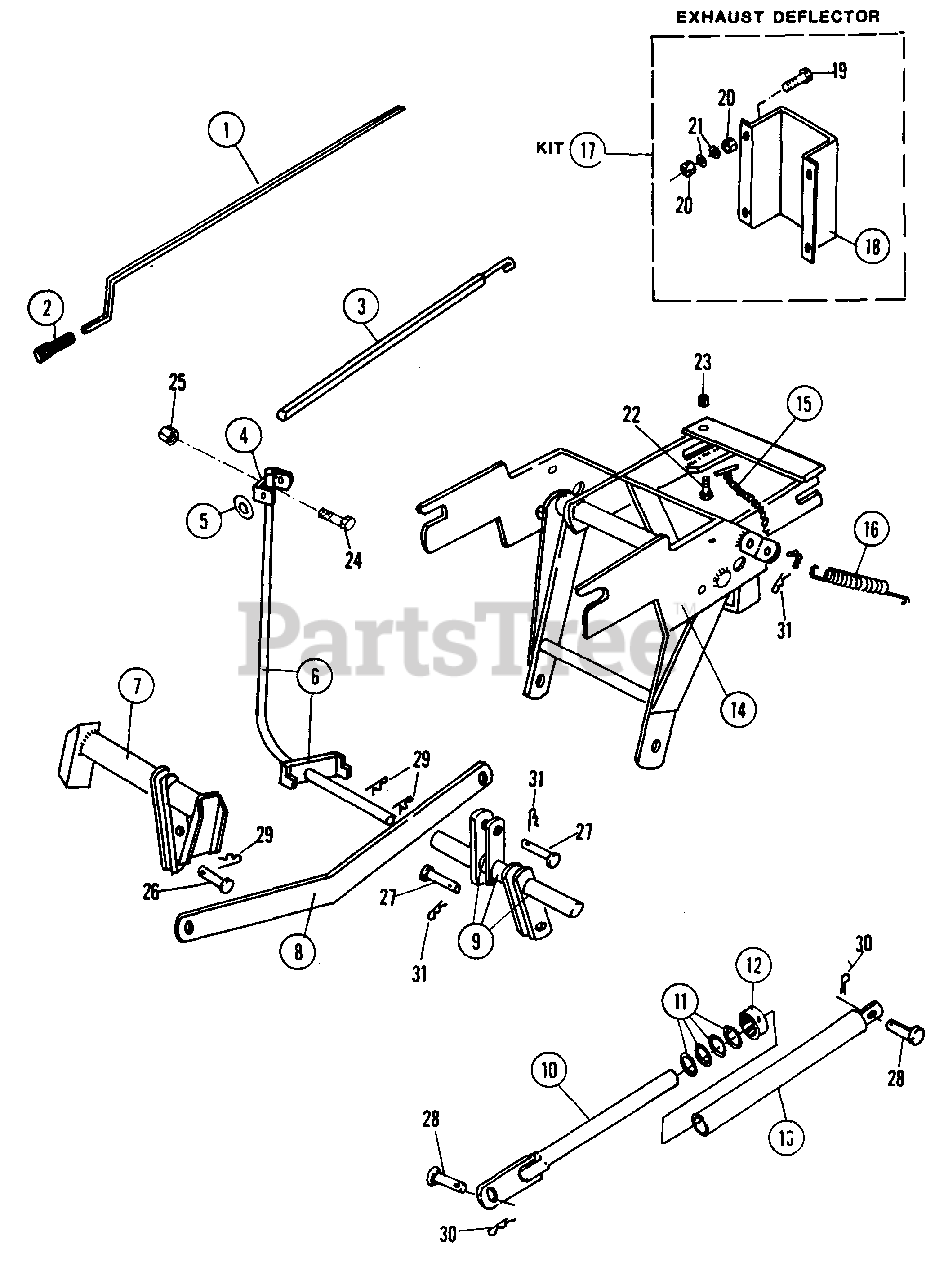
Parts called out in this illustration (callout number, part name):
1	ROD, CHUTE CRANK CONTROL
2	GRIP, HANDLE
3	EXTENSION, CRANK ROD
4	GUIDE, CRANK CONTROL
5	DECAL, CHUTE CONTROL
6	ROD, CRANK SUPPORT
7	LINKAGE, BELLCRANK
8	STRAP, LINK
9	LINKAGE, LIFT
10	ROD, LIFT
11	WASHER, LIFT STOP ADJUSTING
12	COLLAR, LIFT TUBE
13	TUBE, LIFT
14	BRACKET, SNOW THROWER MOUNTING
15	CHAIN, TOGGLE
16	SPRING, LIFT ASSIST.
17	KIT, EXHAUST DEFLECTOR
18	PLATE, EXHAUST DEFLECTOR
19	BOLT, 1/4-20x1" HEX HEAD
20	NUT, 1/4-20 HEX
21	WASHER, 17/16x5/8x.049 FLAT
22	BOLT, 3/8cx1" HEX HEAD
23	LOCKNUT, 3/8c HEX
24	BOLT, 3/8-16x1-1/2 HEX HEAD
25	LOCKNUT, 3/8-16 HEX
26	PIN, LIFT RETAINING CLEVIS
27	PIN, LIFT LINK CLEVIS
28	PIN, LIFT TUBE CLEVIS
29	PIN, HAIR COTTER
30	PIN, COTTER
31	PIN, CHAIN RETAINING HAIR
